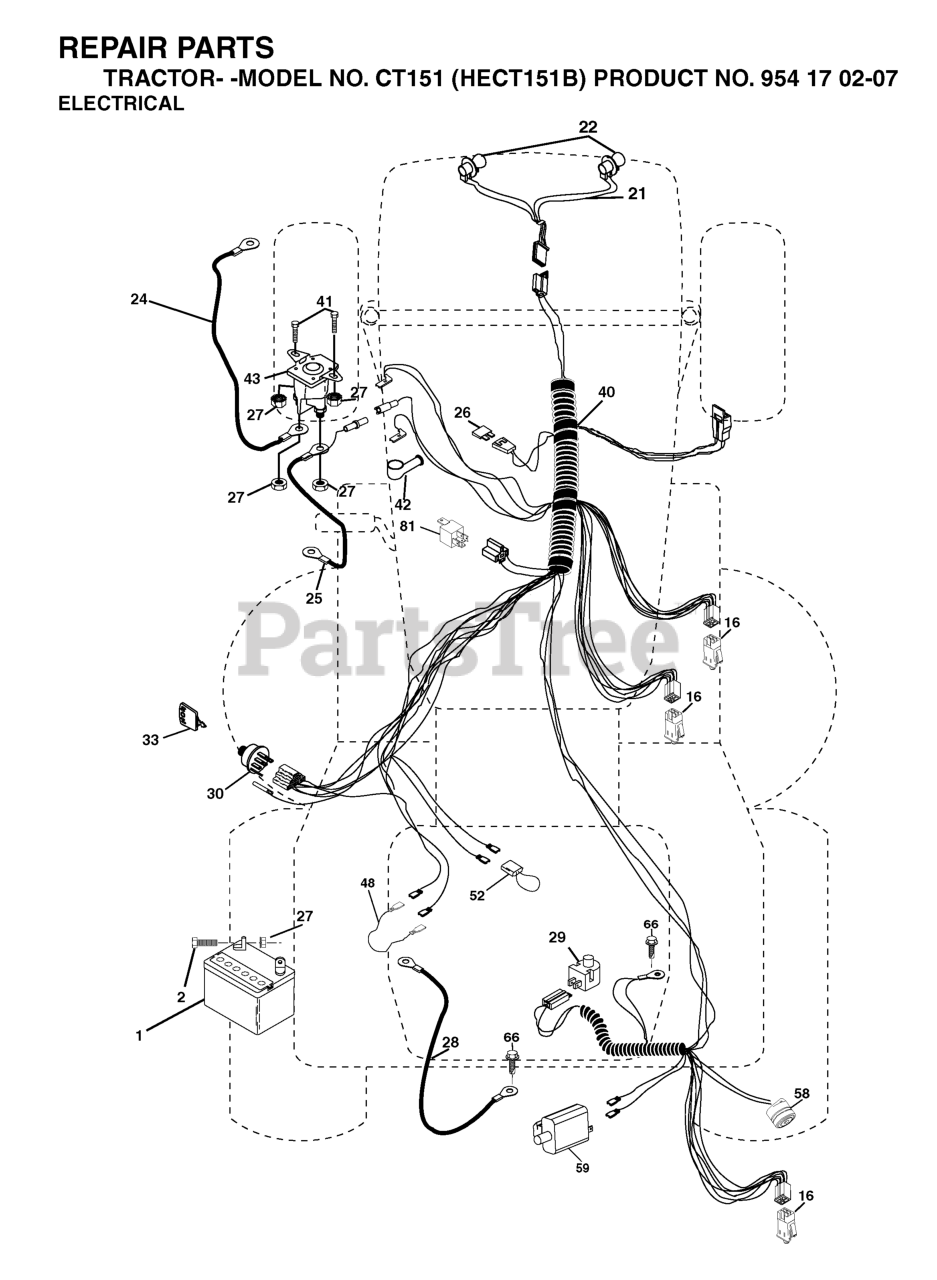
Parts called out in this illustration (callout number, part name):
1	BATTERY 12V .35 AMP
2	BOLT.HEX.1/4.X.3/4.DICHROMATE
16	SWITCH INTERLOOK PUSH-IN
21	HARNESS.W/LIGHT SOCKET
24	BATTERY CABLE GT
25	CABLE BATTERY
26	FUSE 20AMP
27	NUT
28	CABLE GROUND
29	RP.SWITCH.PLUNGER.NC.GRAY
30	IGNITION SWITCH
33	KEY MLD GEN DELTA
41	BOLT
42	TERMINAL COVER
43	SOLENOID
48	ADAPTER.AMMETER
52	WIRE PROTECTION LOOP
58	BUZZER
59	.WITCH.FULL BAGGER.INDICATOR
81	RELAY.ASSY.T
